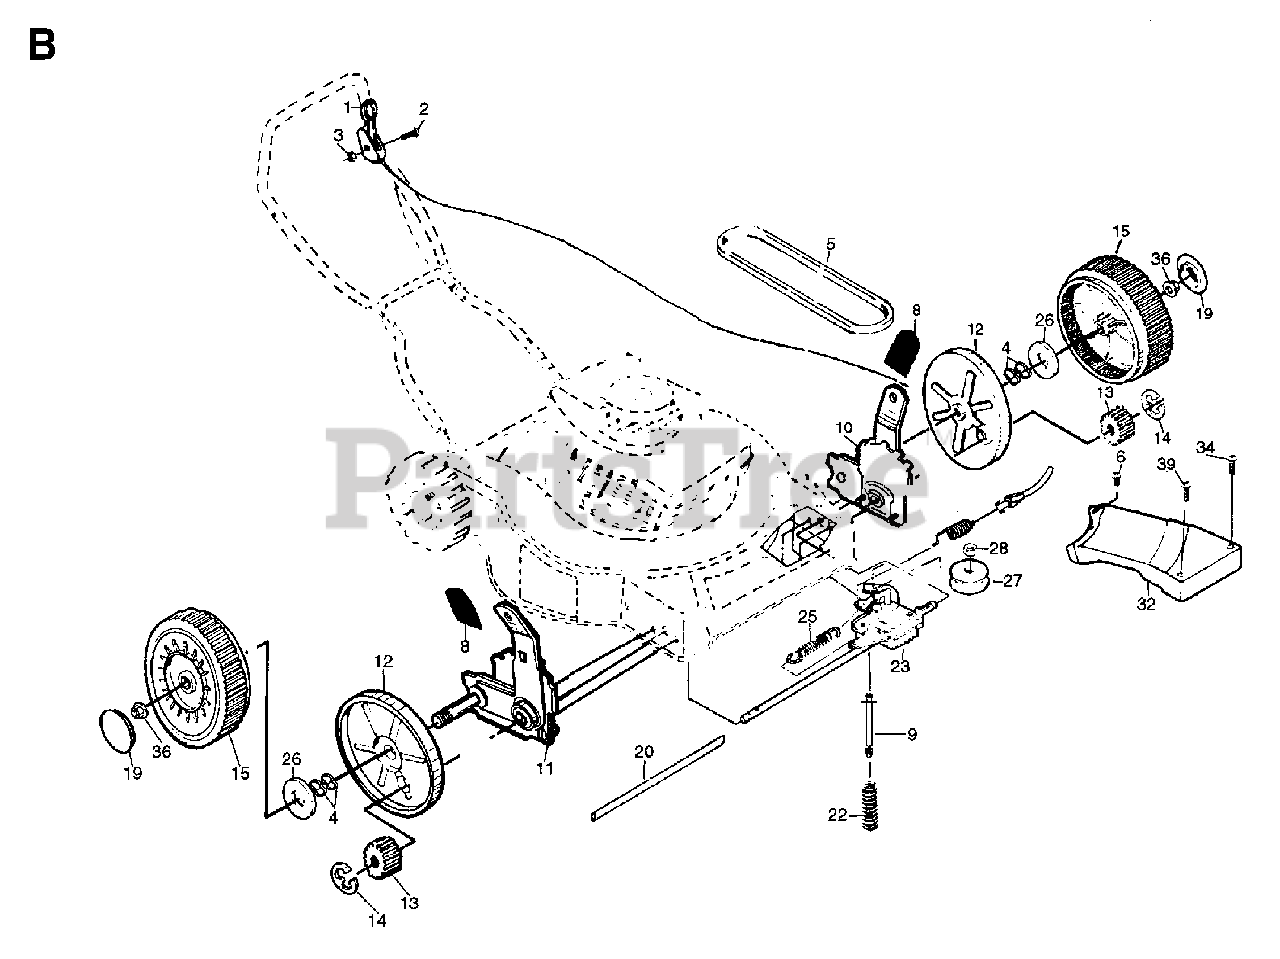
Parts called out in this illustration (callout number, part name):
1	CONTROL
2	SCREW 1/4-20 X 2.12
3	NUT
4	WAVE WASHER
5	BELT THERM .32
8	SELECTOR KNOB
9	SPRING RETAINER
12	DUST SHROUD PM
13	PINION GEAR
14	E-RING 7/16 RE
15	WHEEL & TIRE 8 X 2
20	DRV SHAFT TUBE PM
22	SPRING.EXTENSION
23	GEAR CASE ASMBLY
26	WASHER FLUT
27	PULLEY
28	FLANGED LOCKNUT 3/8-16 ZINC
36	HEX FLANGE LOCKNT
